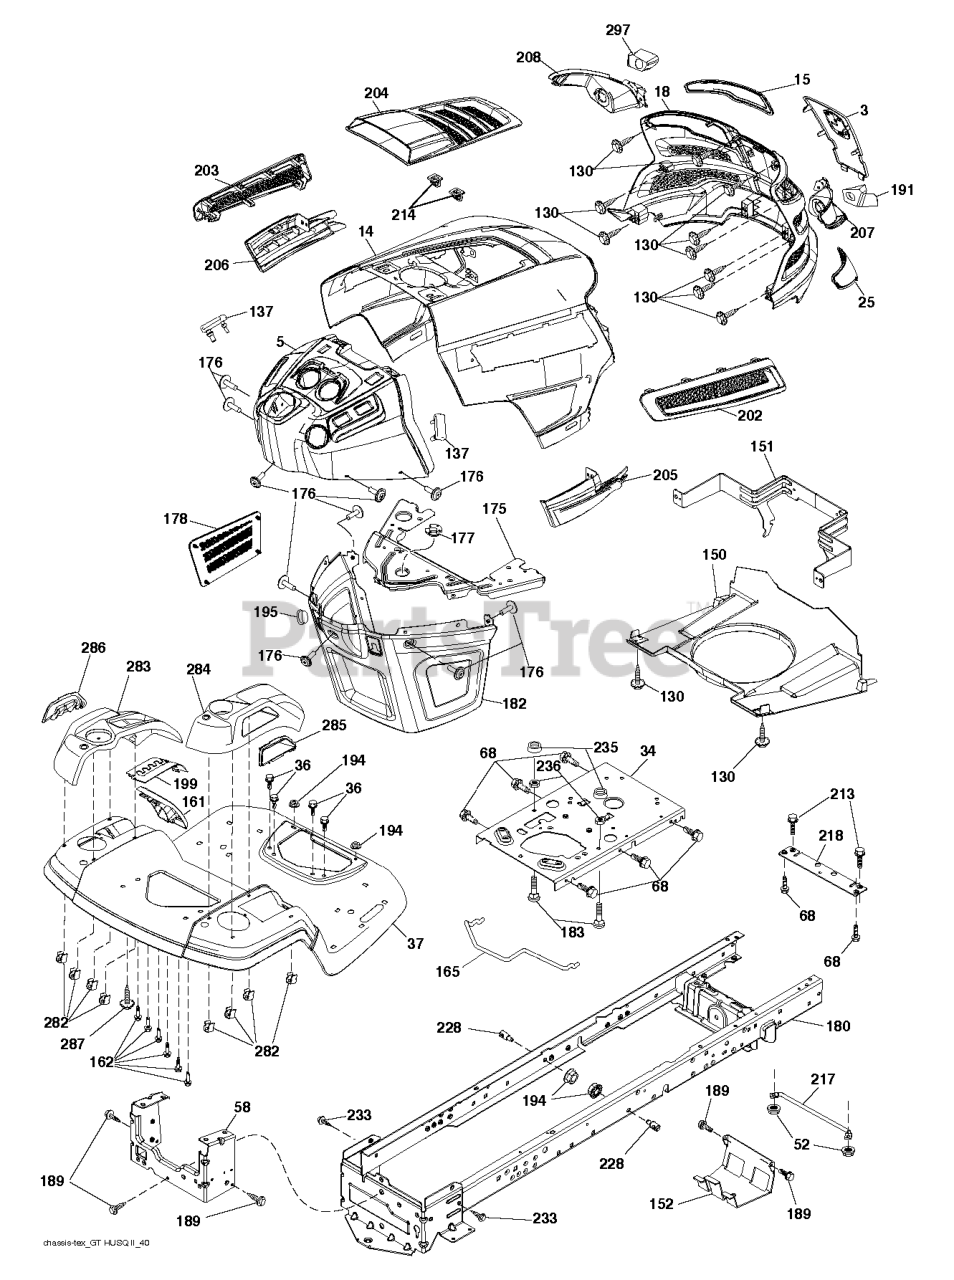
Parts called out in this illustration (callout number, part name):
3	APPLIQUE.SUBASM.GT.HUSQ.II
5	DASH.UPR.ASSY.GT2.SRVMNDER.PTO
14	HOOD.ASM.HUSQVARNA.GT.TEX.ORAN
15	LENS.HEADLIGHT.LH.GTII.2011
18	GRILLE.SUBSTRATE.2011.
25	LENS.HEADLIGHT.RH.GTII.2011
34	PLATE.ENGINE.WELDED.CHASSIS
36	SCREW 5/16"
37	FENDER.TLT.FS.W/CPH/FW/RSF.668
52	LOCKNUT
58	DRAWBAR UPPER 2PC SMALL FENDER
68	Screw 5/16-18 x 1/2 Hex, Self Tapping 5/16-18 x 1/2
130	SCREW.#10 X 0.750.BOS
137	BUMPER DASH
150	AIR.DUCT.GTV.BLACK
151	BRACKET.PIVOT.HOOD.GT.HUSQ.II
152	SHIELD.BROWNING.W/TEX
161	WINDOW FUEL
162	SCREW.HI-LO.CONSOLE
165	SUPPORT.TANK.REAR.W/TEX
175	PLATE.CROSSMEMBER.HUSQ
176	SCREW.#10-24X5/8.RN.QU
177	BUSHING, STEERING
178	CARGO.ASM.NET.TXGT.W/C
180	CHASS.WLDMNT.TL.12GA/2P.48/54
182	DASH.LOWER.COMMON.12V.ADAPTOR
183	BOLT.5/16-18X1-1/4 FULL THD
189	SCREW
191	INSERT.REFLECTIVE.RH.HUSQ.GTII
194	NUT LOCK HEX FLANGE 5/16-18
195	PLUG.HOLE.DASH.LOWER.12V.BLK
199	PLATE.DECK.LIFT.HUSQ.LT
202	VENT.SIDE.RH.GT.HUSQ.II.
203	VENT.SIDE.LH.GT.HUSQ.II.498
204	VENT.TOP.HUSQ.GT2
205	SIDE.TRIM.RH.GT.HUSQ.II
206	SIDE.TRIM.LH.GT.HUSQ.II.GRAY
207	BEZEL LIGHT.RH.GT.II.MYLAR
208	BEZEL LIGHT.LH.GT.II.MYLAR
213	BOLT
214	CLIP.RETAINER.TINNER.
217	ROD.PIVOT.HOOD
218	X-PIECE.HOOD.STOP.NON/
228	STUD.FASTNER.W/ANTI-ROTATE
233	BOLT.SHOULDER
235	SPACER FENDER
236	NUT.CENTERLOCK.5/16-
282	CLIP.RETAINER.CONSOLE.LT.HUSQ
283	CONSOLE.DECK.LFT.R.SDFL.HUSQLT
284	CONSOLE.CNTRL.
285	CONSOLE INSERT RH
286	CONSOLE.INSRT.LH.HUSQ.LT.BLACK
287	SCREW 1/4X20
297	INSERT.REFLECTIVE.LH.HUSQ.GTII
